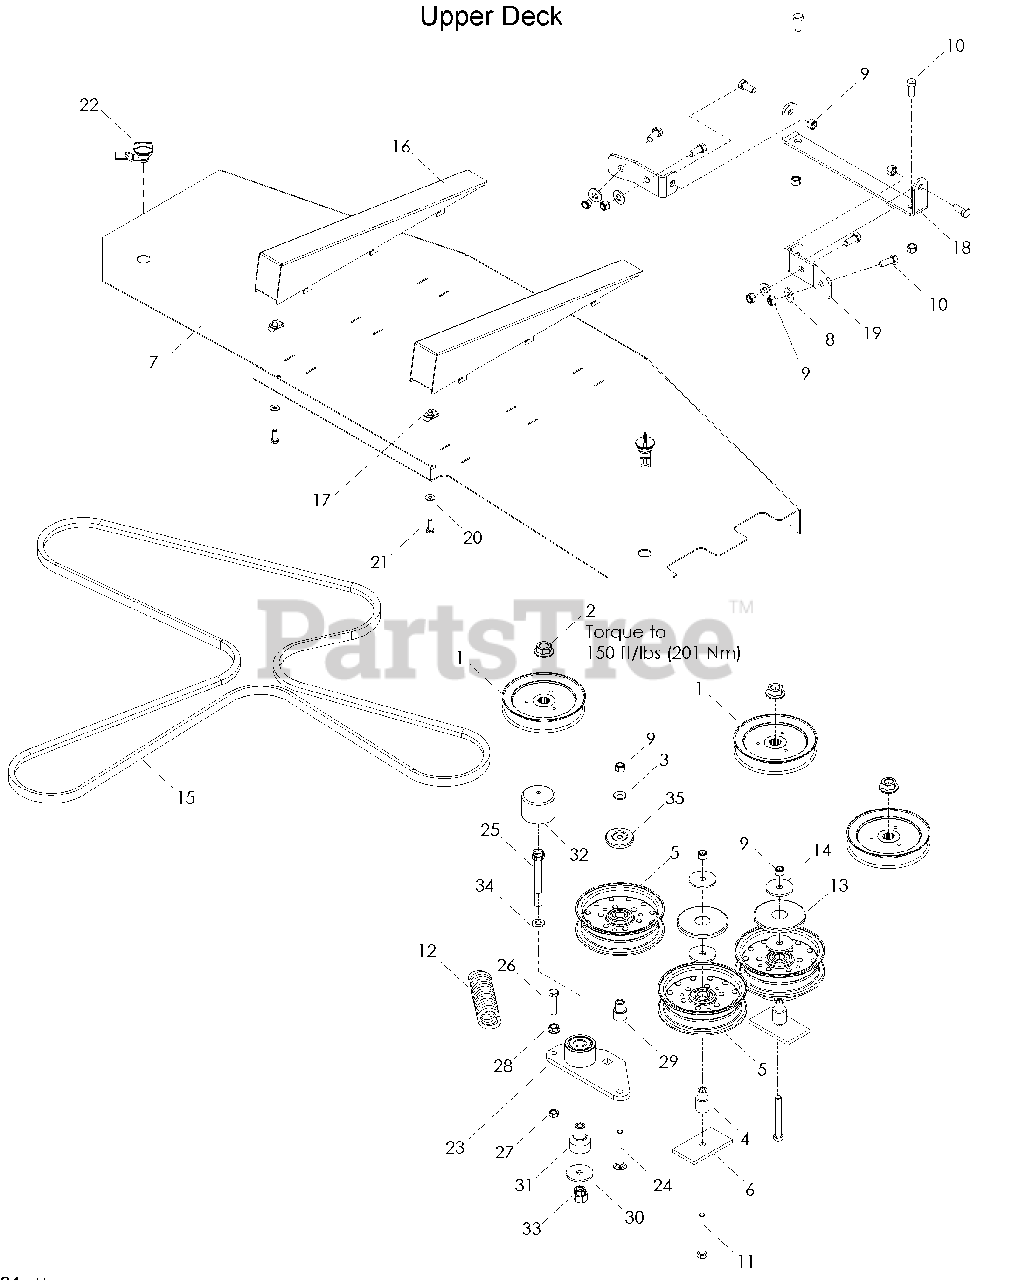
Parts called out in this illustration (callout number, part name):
2	NUT 3/4-16 FLANGE
3	WASHER, THICK 3/8
4	BUSHING, IDLER
5	PULLEY, IDLER
6	PAD, PAINTED
7	COVER, BELT, 52
8	WASHER 3/8 FLAT
9	NUT 3/8-16 HEX NYLOC
10	HCS 3/8-16 x 7/8
11	HCS 3/8-16 x 3
13	DUST CAP, TOP
14	WASHER, 3/8 SPECIAL
15	BELT, DECK 52
17	RETAINER 1/4-20 "U" TYPE
18	HINGE, BIN
19	BASE, HINGE
20	WASHER, 1/4 FLAT SAE
21	HCS 1/4-20 x 3/4
22	LATCH, SHORT WING
23	ARM, IDLER, W/BEARINGS
24	RHSNB 3/8-16 x 2 3/4
25	HCS 1/2-13 x 3 1/4
26	HCS 3/8-16 x 1 1/2 GR 8
27	NUT 3/8-16 HEX JAM
28	NUT 3/8-16 HEX WHIZLK
29	BUSHING, IDLER
30	WASHER, SUPPORT
31	PIVOT, BEARING
32	CAP, VINYL
33	NUT 1/2 HEX NYLOC
34	WASHER, BELLEVILLE 1/2
35	SHIELD, DUST
